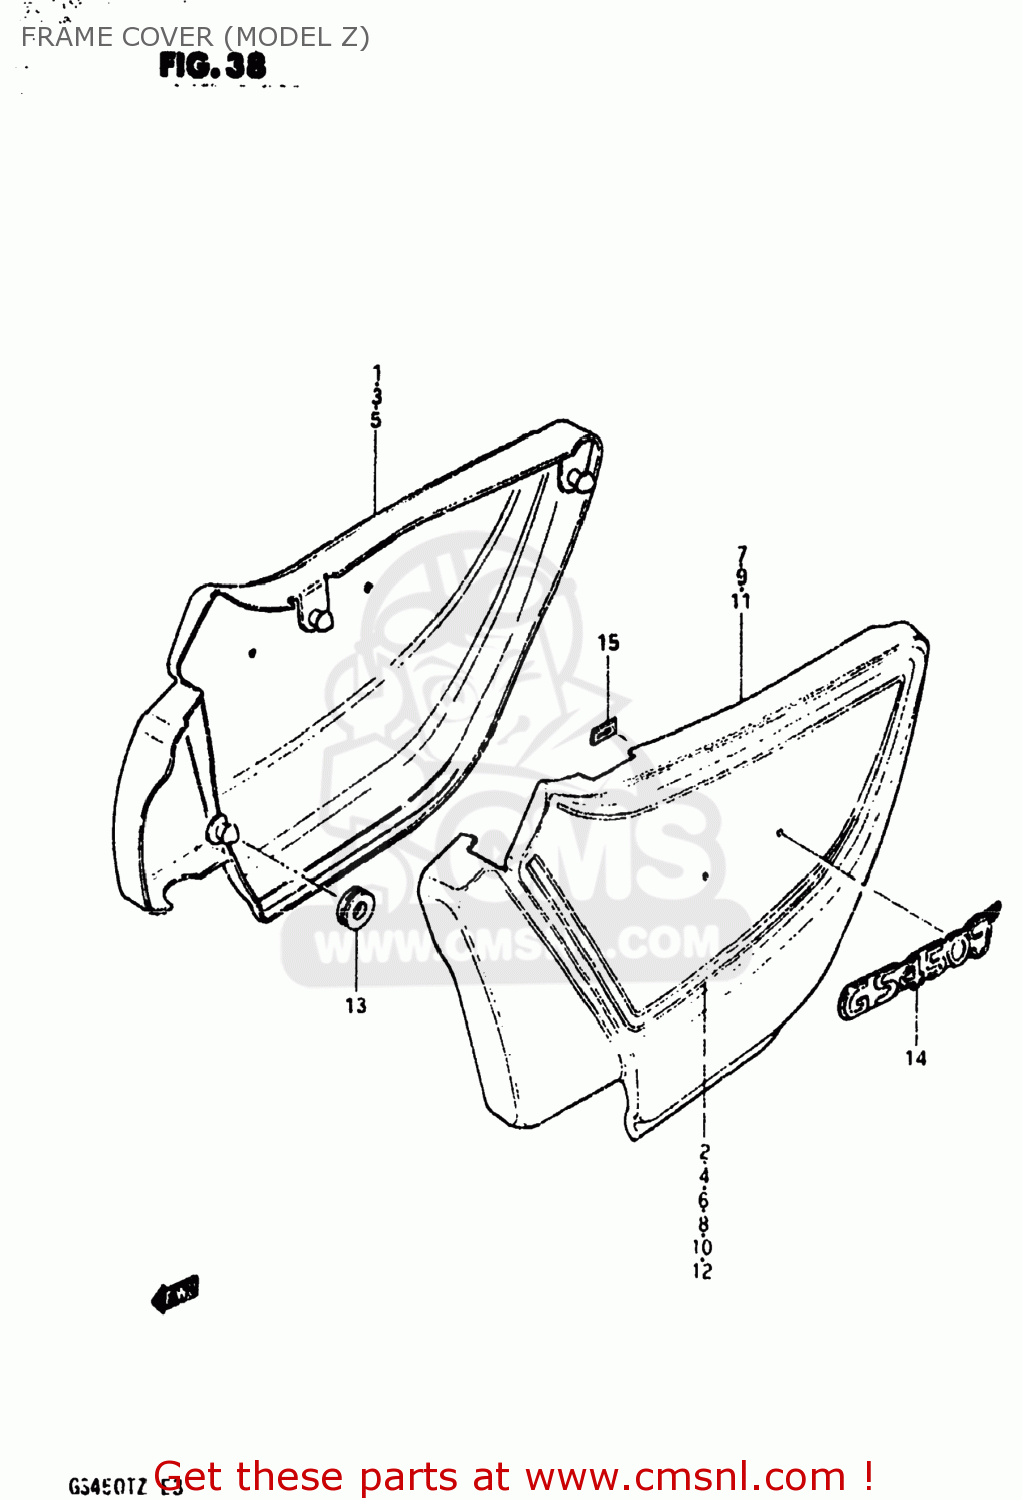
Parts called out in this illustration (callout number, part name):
1	COVER,FRAME,RIGHT
2	TAPE SET,FRAME COVER
3	COVER,FRAME,RIGHT
4	TAPE SET,FRAME COVER
5	COVER,FRAME,RIGHT
6	TAPE SET,FRAME COVER
7	COVER,FRAME,LEFT
8	TAPE SET,FRAME COVER
9	COVER,FRAME,LEFT
10	TAPE SET,FRAME COVER
11	COVER,FRAME,LEFT
12	TAPE SET,FRAME COVER
13	CUSHION
14	EMBLEM,FRAME COVER
15	NUT
